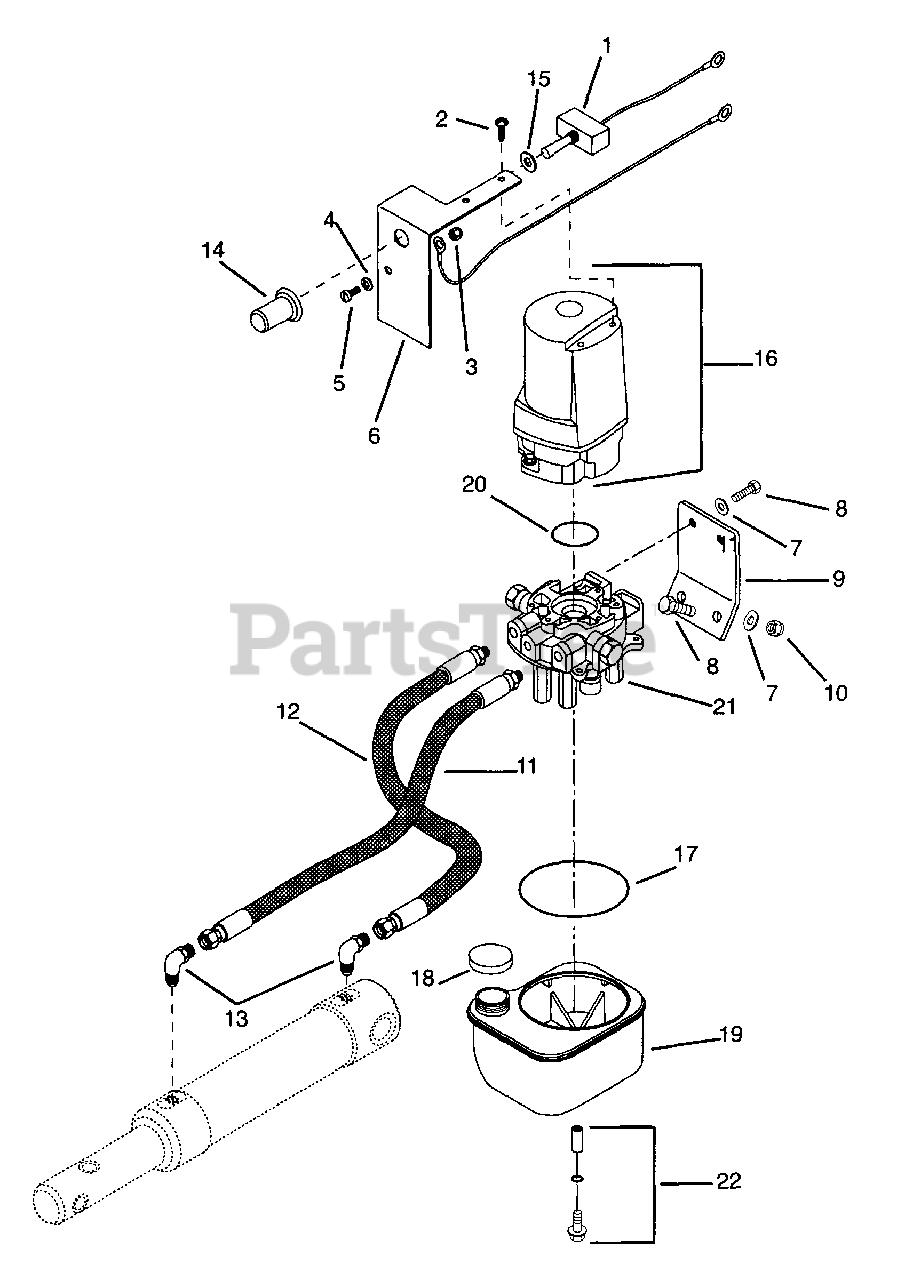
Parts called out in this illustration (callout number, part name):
1	Assembly-Switch
2	Screw-Tapping 12-14 x .50
3	Nut-Locking-Nylon .250-20 Grade 2
4	Washer-Flat-Steel .281 x .625 x .065
5	Screw-Machine .25-20
6	Switch Plate
7	Washer-Flat-Steel .406 x .812 x .065
8	Bolt-Hex .375-16 x 1.00 Grade 5
9	Lift Pump Mounting Bracket
10	Nut-Locking-Nylon .375-16 Grade 2
11	Assembly, Hose Pump to Cylinder
12	Assembly, Hose Pump to Cylinder
13	Adapter 2503-4-4
14	Boot, Switch
15	Washer-Flat-Steel .505 x .880 x .072
16	Assembly-Motor
17	Reservoir Seal-O-Ring
18	Reservoir-Cap
19	Reservoir-Tank
21	Assembly-Adaptor
22	Assembly-Screw-O-Ring and Spacer
